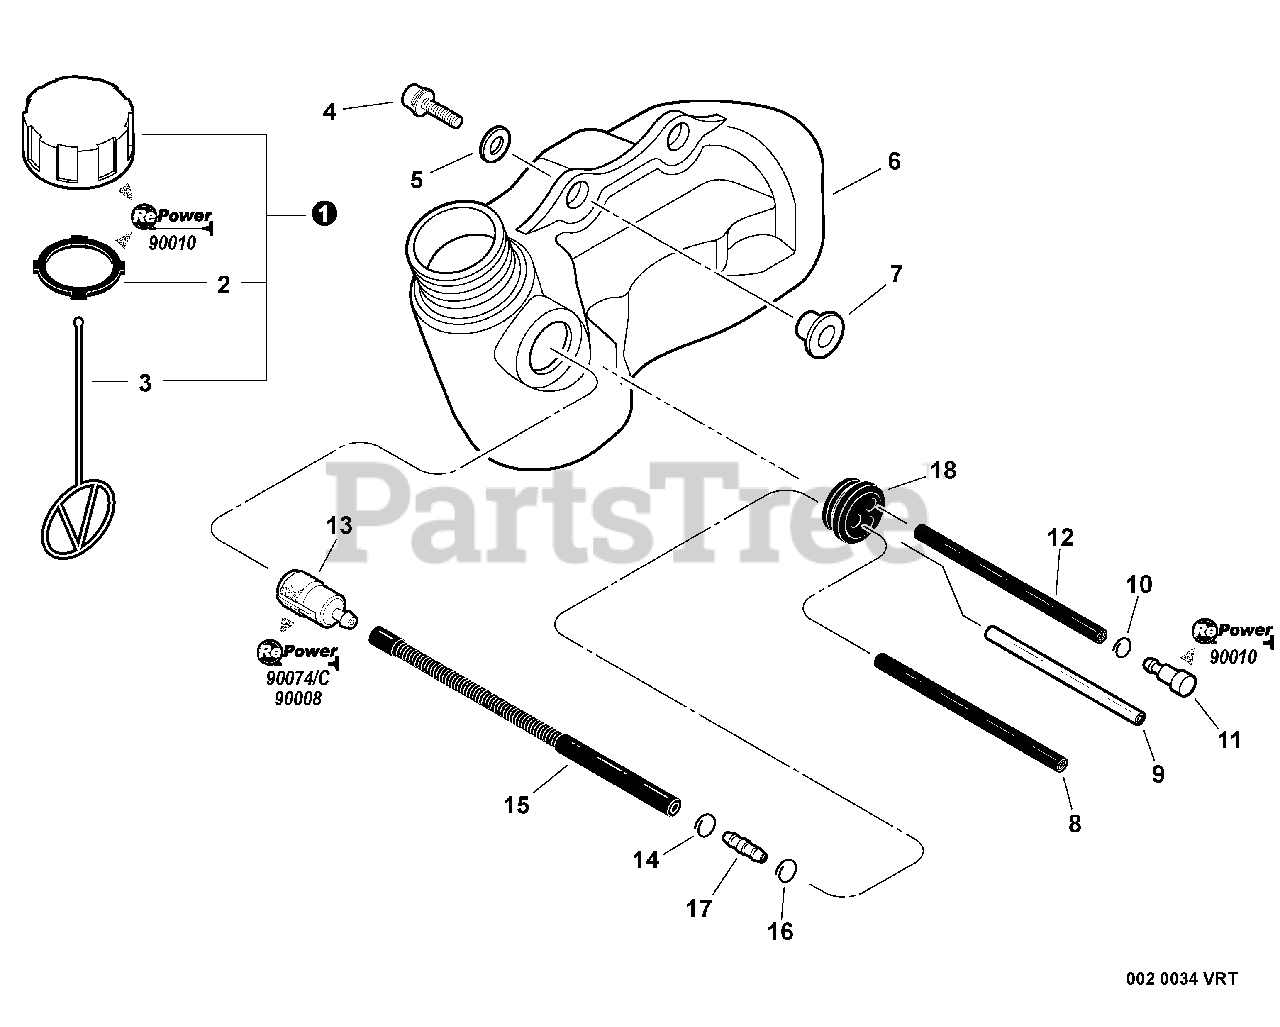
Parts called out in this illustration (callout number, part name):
1	CAP ASSY
2	GASKET, CAP
3	CONNECTOR, CAP
4	SCREW - 5X20
5	WASHER - 5
6	TANK, FUEL
7	COLLAR - 5
8	PIPE - 3X6X105 -- BLACK
9	PIPE - 3X6X75 -- CLEAR
10	CLIP - 6.6
11	VENT, FUEL TANK
12	PIPE - 3X6X65 -- BLACK
13	FILTER, FUEL
14	CLIP - 6.5
15	PIPE, FUEL - CORRUGATED
16	CLIP - 6
17	CONNECTOR, PIPE
18	GROMMET
19	RePower FILTER KIT
20	Repower CAP AND VENT KIT
21	RePower TUNE-UP KIT
